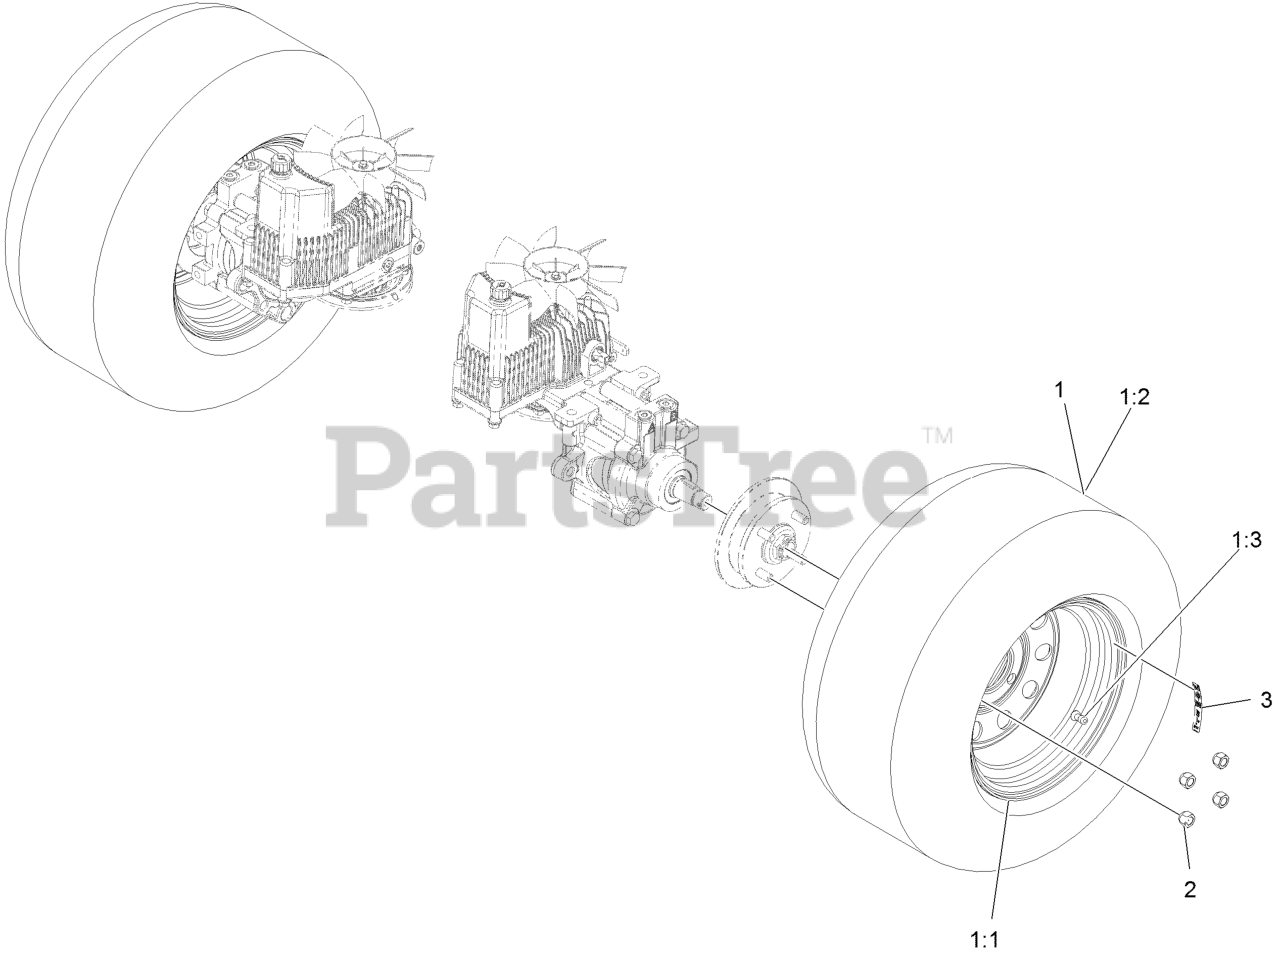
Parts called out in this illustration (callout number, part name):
1	WHEEL AND TIRE ASM
1:3	Stem-Valve
2	NUT-LUG
3	DECAL-TORQUE, WHEEL HUB LUG
